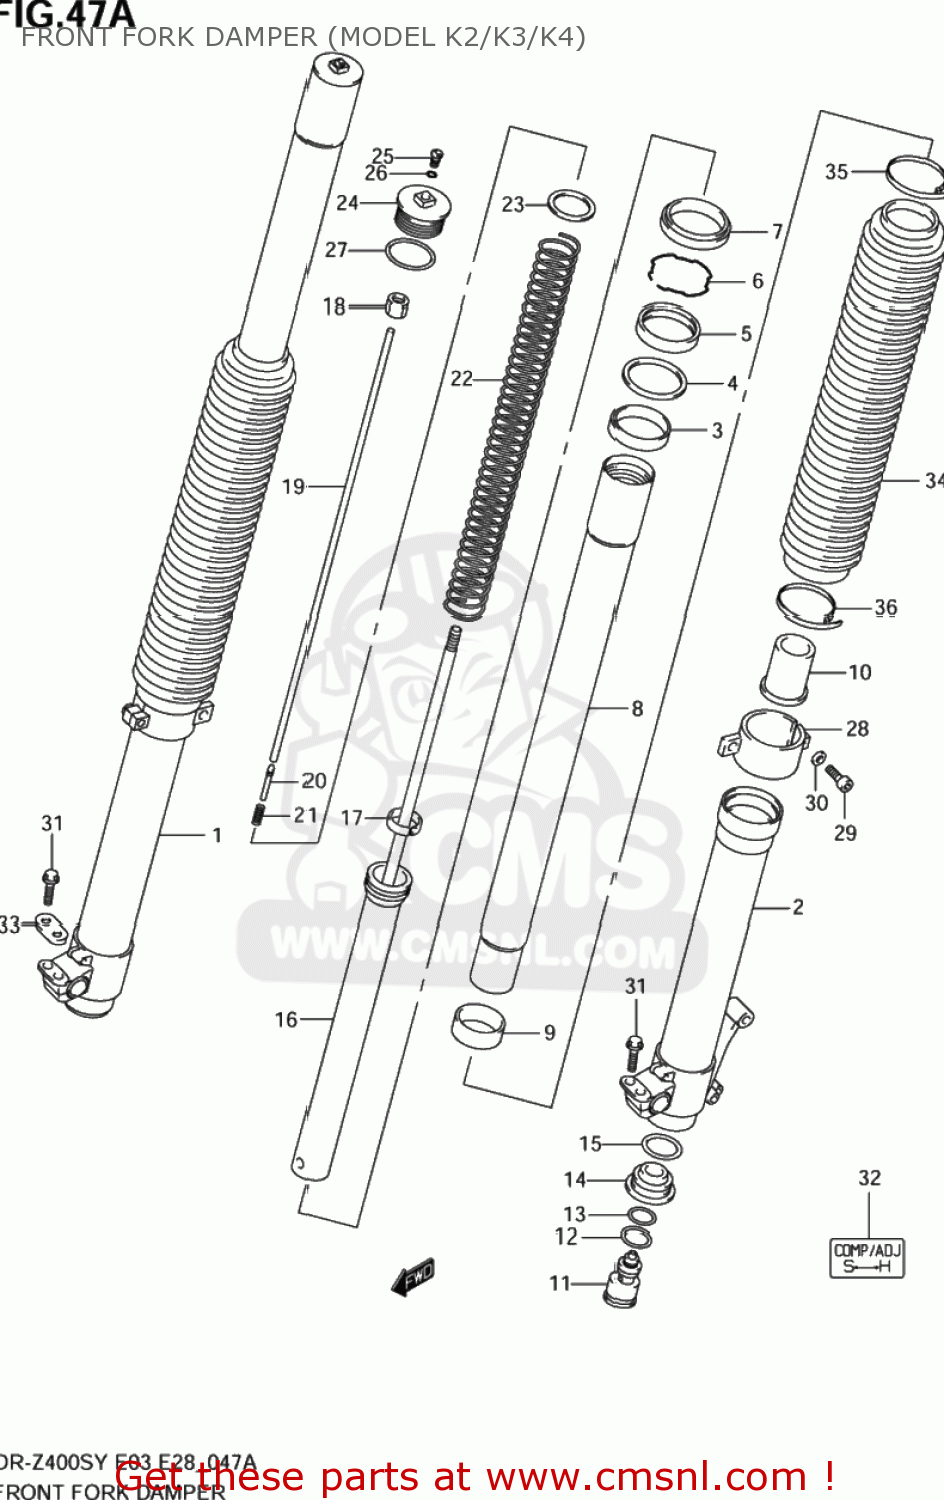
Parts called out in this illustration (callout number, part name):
1	TUBE,OUTER,R
2	TUBE,OUTER,L
3	BUSH,GUIDE
4	SPACER,SEAL
5	SEAL,OIL
6	RING,STOPPER
7	SEAL,DUST
8	TUBE,INNER
9	BUSH,SLIDE
10	PIECE,OIL LOCK
11	BOLT,CTR
12	O RING
13	O RING
14	PLATE,END
15	O RING
16	ROD,FR DAMPER
17	BUSH,SLIDE
18	NUT
19	ROD,PUSH
20	NEEDLE
21	SPRING,PUSH ROD
22	SPRING,FR(K=8.63N/0.88KG)
23	JOINT,SPRING
24	BOLT,FORK
25	BOLT,PLUG
26	O RING,PLUG
27	O RING
28	HOLDER,BOOT
29	BOLT
30	WASHER(5.5X10X1)
31	BOLT,HANDLE HOLDER(8X35)
32	LABEL
33	COVER,AXLE HOLDER
34	BOOT
35	BAND,BOOT UPR
36	BAND,BOOT LWR
